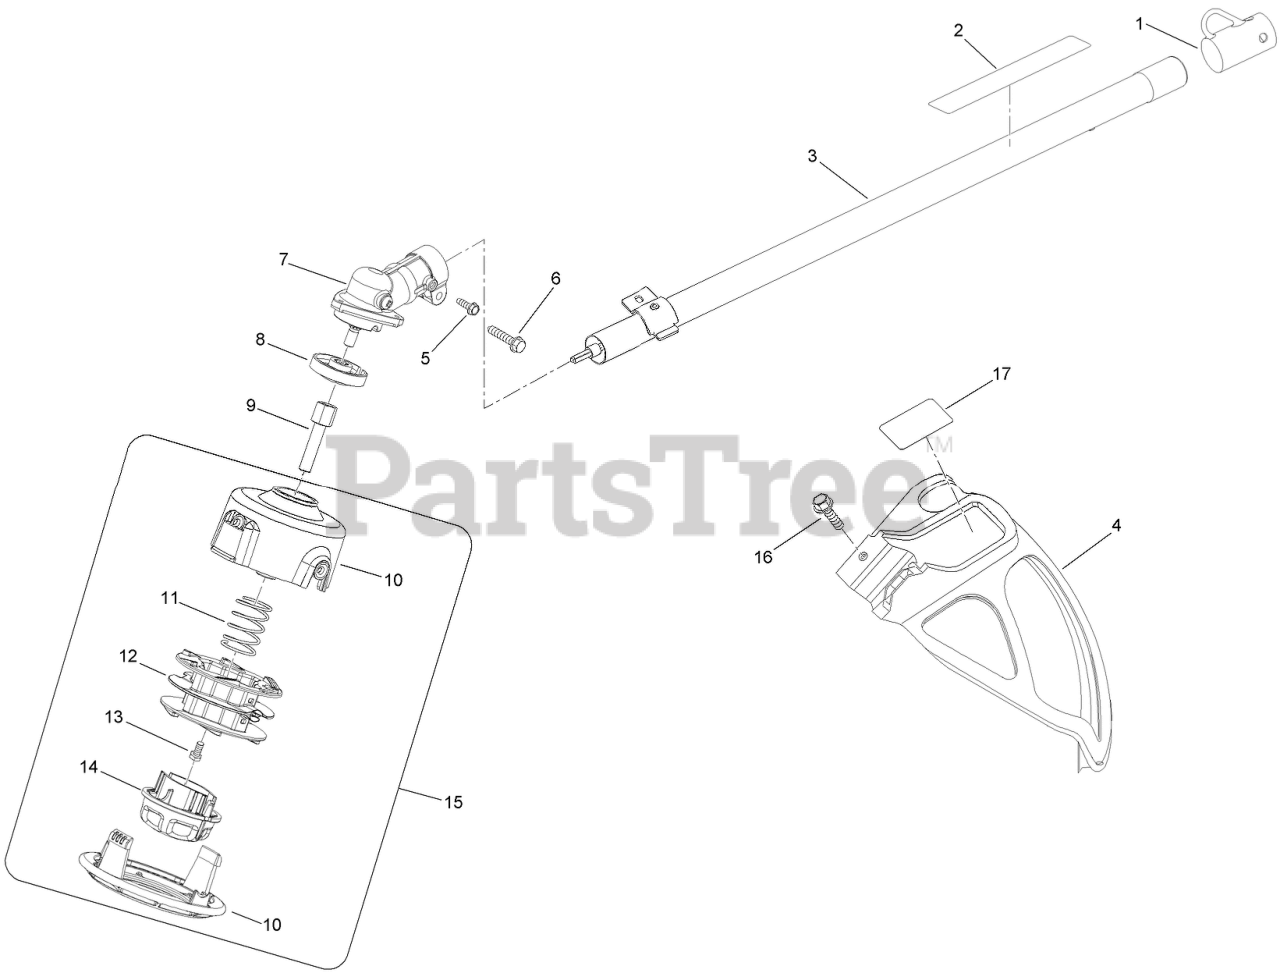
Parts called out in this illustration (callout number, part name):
1	CAP-HANGER
2	DECAL-WARNING
3	SHAFT ASM
4	GRASS DEFLECTOR ASM
5	SCREW-HWH
7	HEAD-GEAR
9	ADAPTOR-HEAD SHAFT, TRIMMER
11	SPRING-COMPRESSION
14	KNOB-BUMP
16	SCREW-HWH
17	DECAL-GRASS DEFLECTOR
